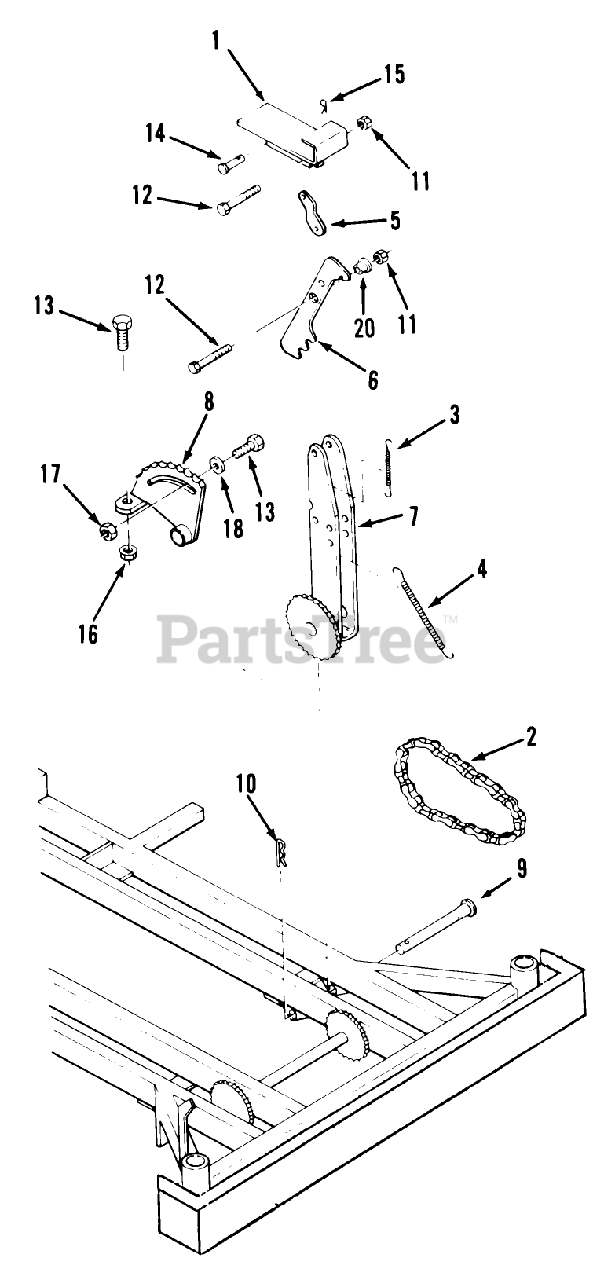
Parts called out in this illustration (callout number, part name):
3	Spring
4	Extension Spring
6	LIFT-ARM PWL *B
7	ASSY-LVR ARM 1022 *B
9	PIN-PEDAL
10	Hairpin
17	HEX-STOP NUT N-140
18	WASHER 5/16 SAE
20	BUSHING-PDL
